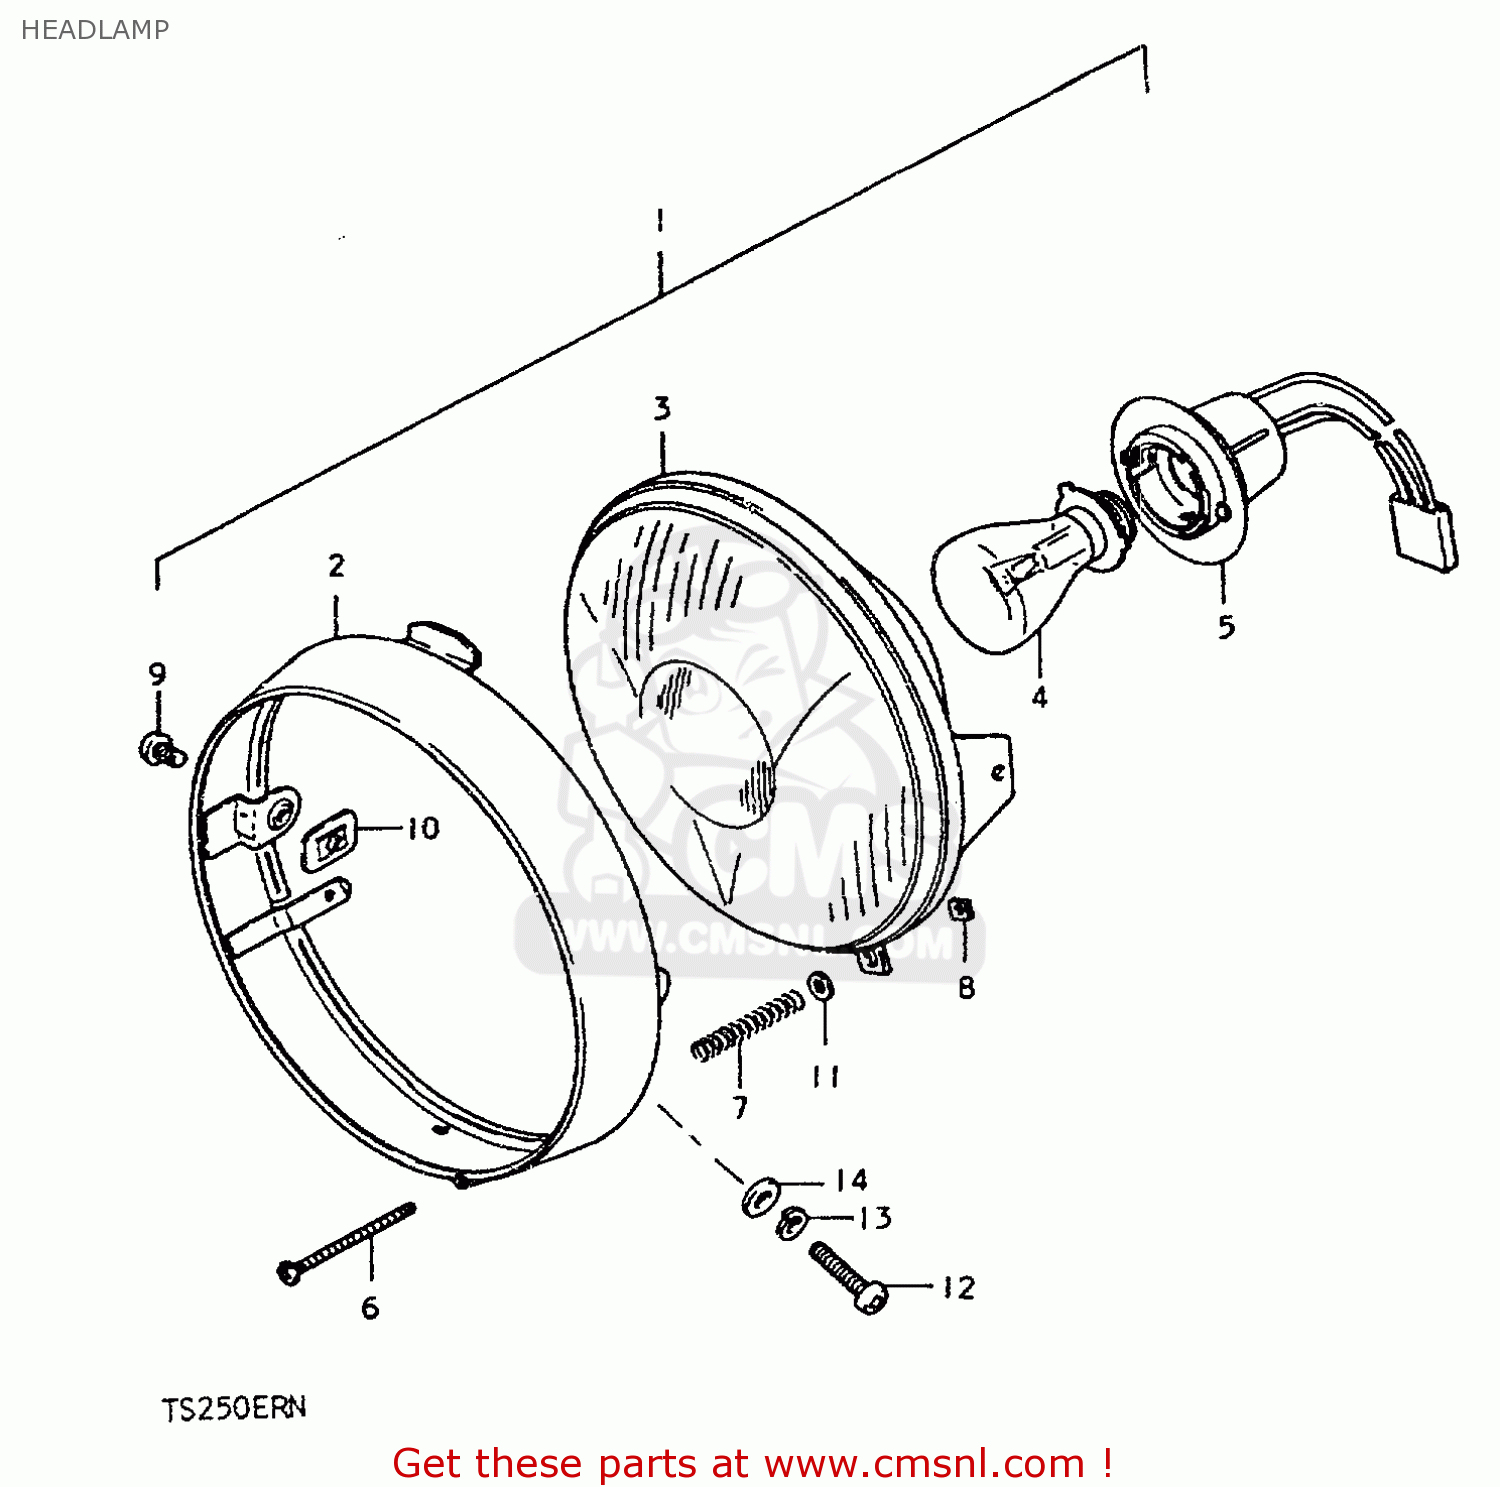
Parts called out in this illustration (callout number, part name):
1	HEADLAMP ASSY
2	RIM
3	LAMP UNIT
4	BULB(6V25/25W,STANLEY,A7007)
5	SOCKET,HEADLAMP
6	SCREW,HEADLAMP ADJUST
7	SPRING
8	NUT,HEADLAMP ADJUSTER
9	SCREW
10	NUT
11	WASHER
12	SCREW
13	LOCK WASHER
14	WASHER
